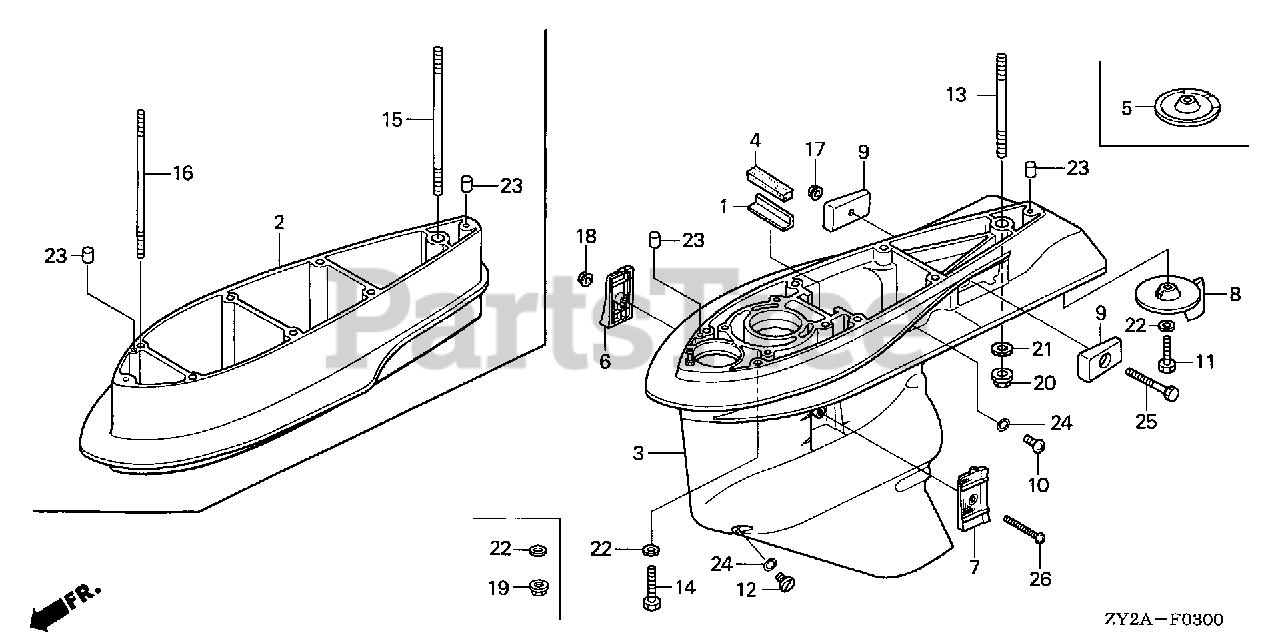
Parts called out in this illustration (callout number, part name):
1	PLATE, RUBBER SETTING
3	CASE, GEAR *NH282MU* (OYSTER SILVER METALLIC-U)
4	GROMMET, GEAR CASE
5	COVER, GEAR CASE *NH282MU* (OYSTER SILVER METALLIC-U)
6	SCREEN, R. WATER
7	SCREEN, L. WATER
9	METAL, ANODE
10	BOLT, OIL CHECK
11	BOLT, HEX. (10X32)
12	BOLT, DRAIN PLUG
13	BOLT, STUD (12X40)
14	BOLT, HEX. (10X47)
17	NUT, SELF-LOCK (6MM)
18	NUT, SELF-LOCK (5MM)
20	NUT, SELF-LOCK (12MM)
21	WASHER, PLAIN (12MM)
22	WASHER, PLAIN (10MM)
23	PIN, DOWEL (6X10)
24	O-RING (6.9X1.45)
25	BOLT, HEX. (6X55)
26	SCREW, OVAL (5X45)
